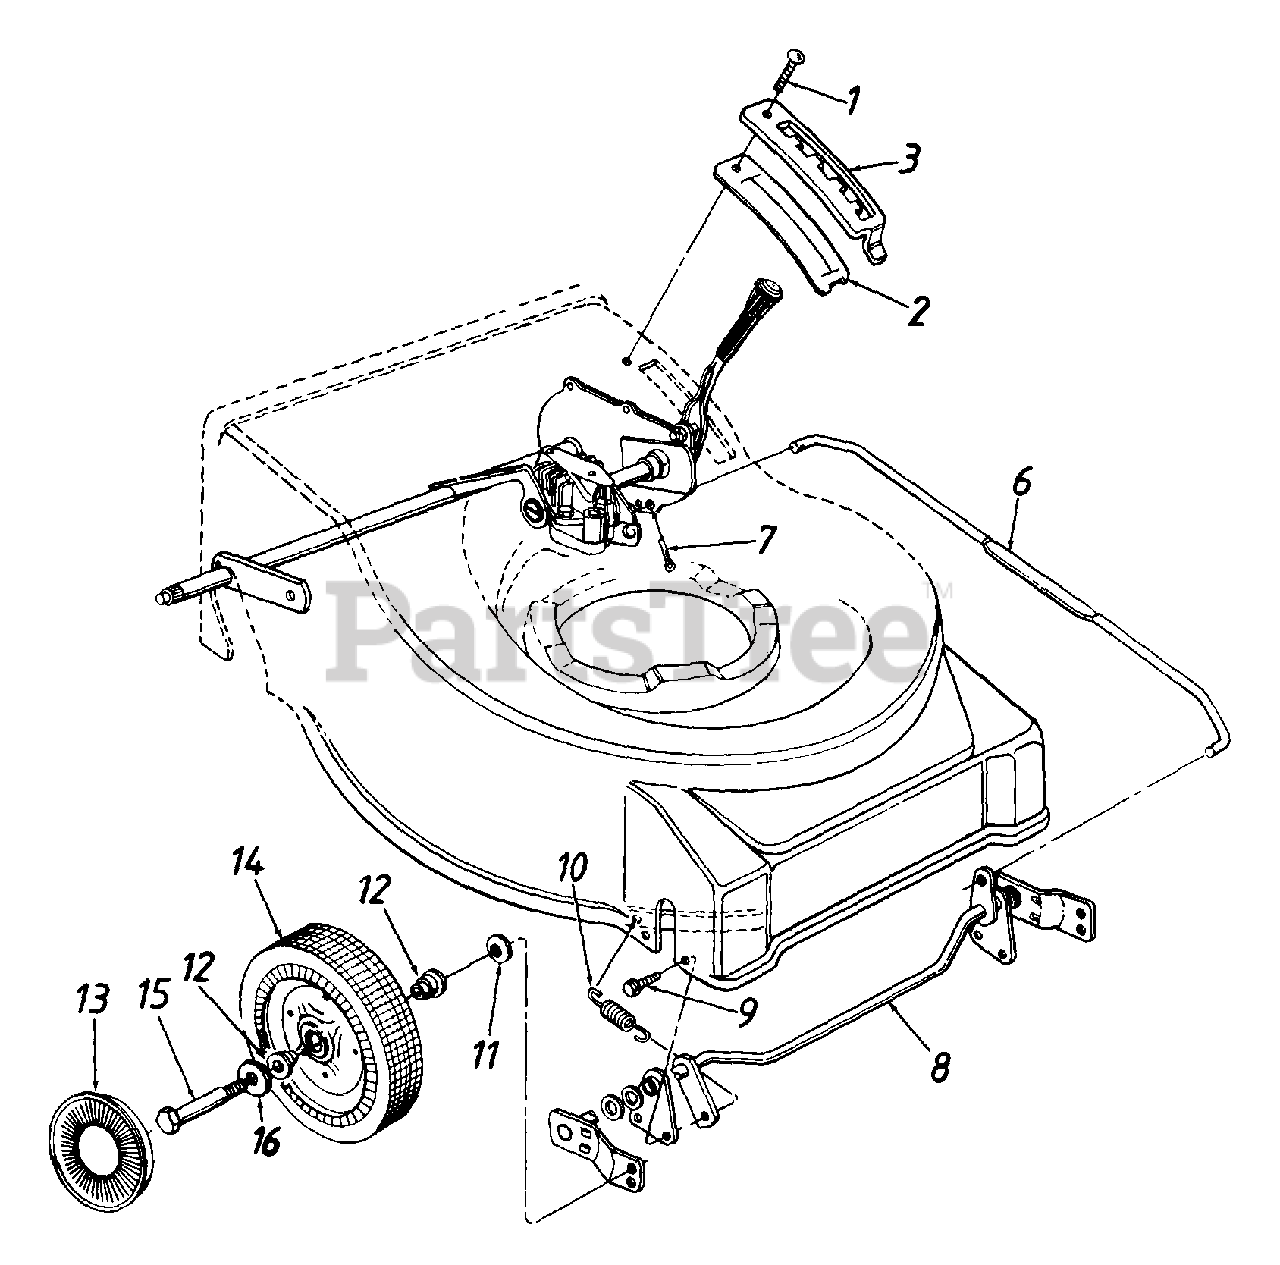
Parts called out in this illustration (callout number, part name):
1	Torx Mach. AB-Tap Scr. 1/4 x .62" Lg.
2	Height Adjustment Support
3	Height Adjustment Plate
6	Height Adj. Connecting Rod
7	Cotter Pin 3/32" Dia.
8	Front Axle Ass'y.
9	Hex L-Wash. Hd. AB-Tap Scr. 1/4 x .38" Lg.
10	Extension Spring 2.39" Lg.
11	Bell-Wash. .380" I.D. x .88"
12	Ball Bearing 1/2" I.D.
13	Hub Cap
14	Wheel Ass'y. Comp. - Front
15	Shld. Bolt .498" Dia. x 1.45"
16	Wave Wash. .51" I.D. x .78"
